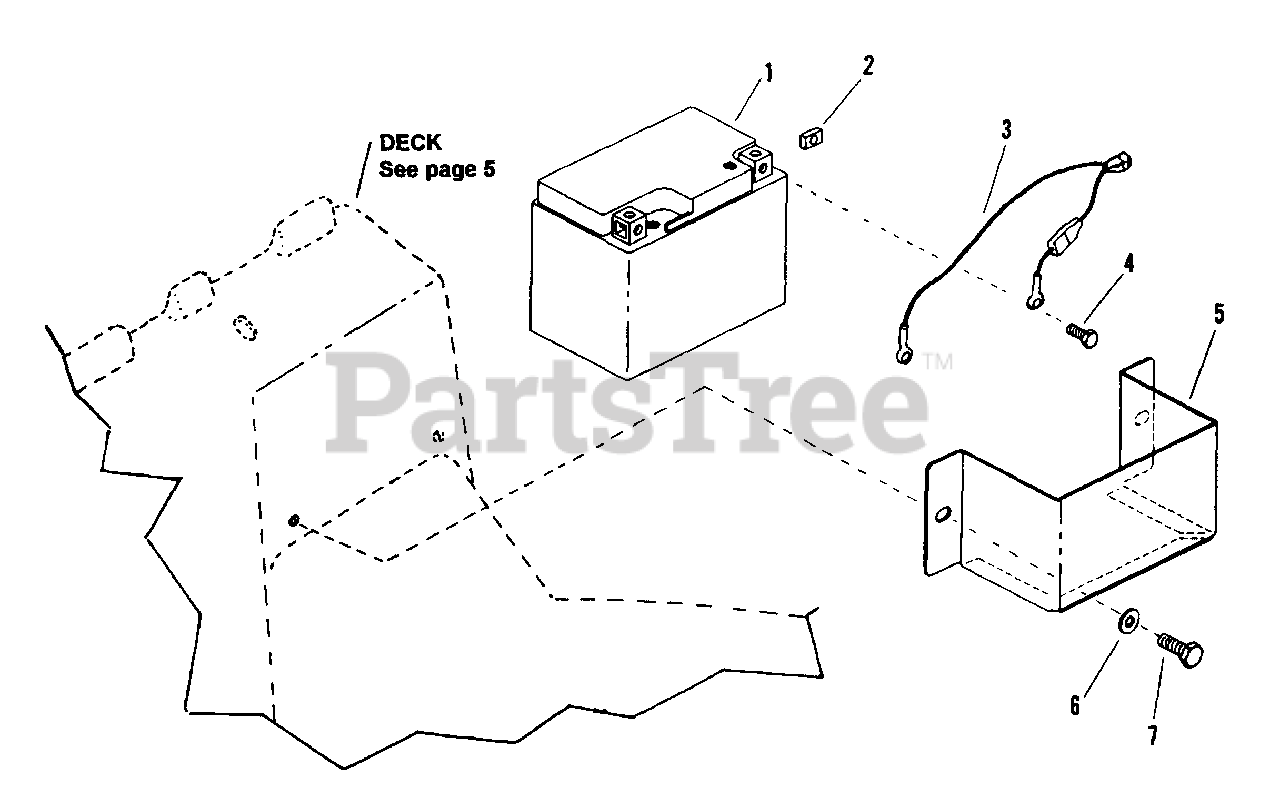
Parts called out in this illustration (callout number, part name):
1	BATTERY, 12 Volt
2	NUT, Battery Terminal
3	HARNESS, Battery
4	SCREW, M5 x 10mm Cross Recess Pan Head
5	BRACKET, Battery Support
6	WASHER, 1/4" Split Lock
7	SCREW, 1/4-20 x 3/4" Hex Head Cap
